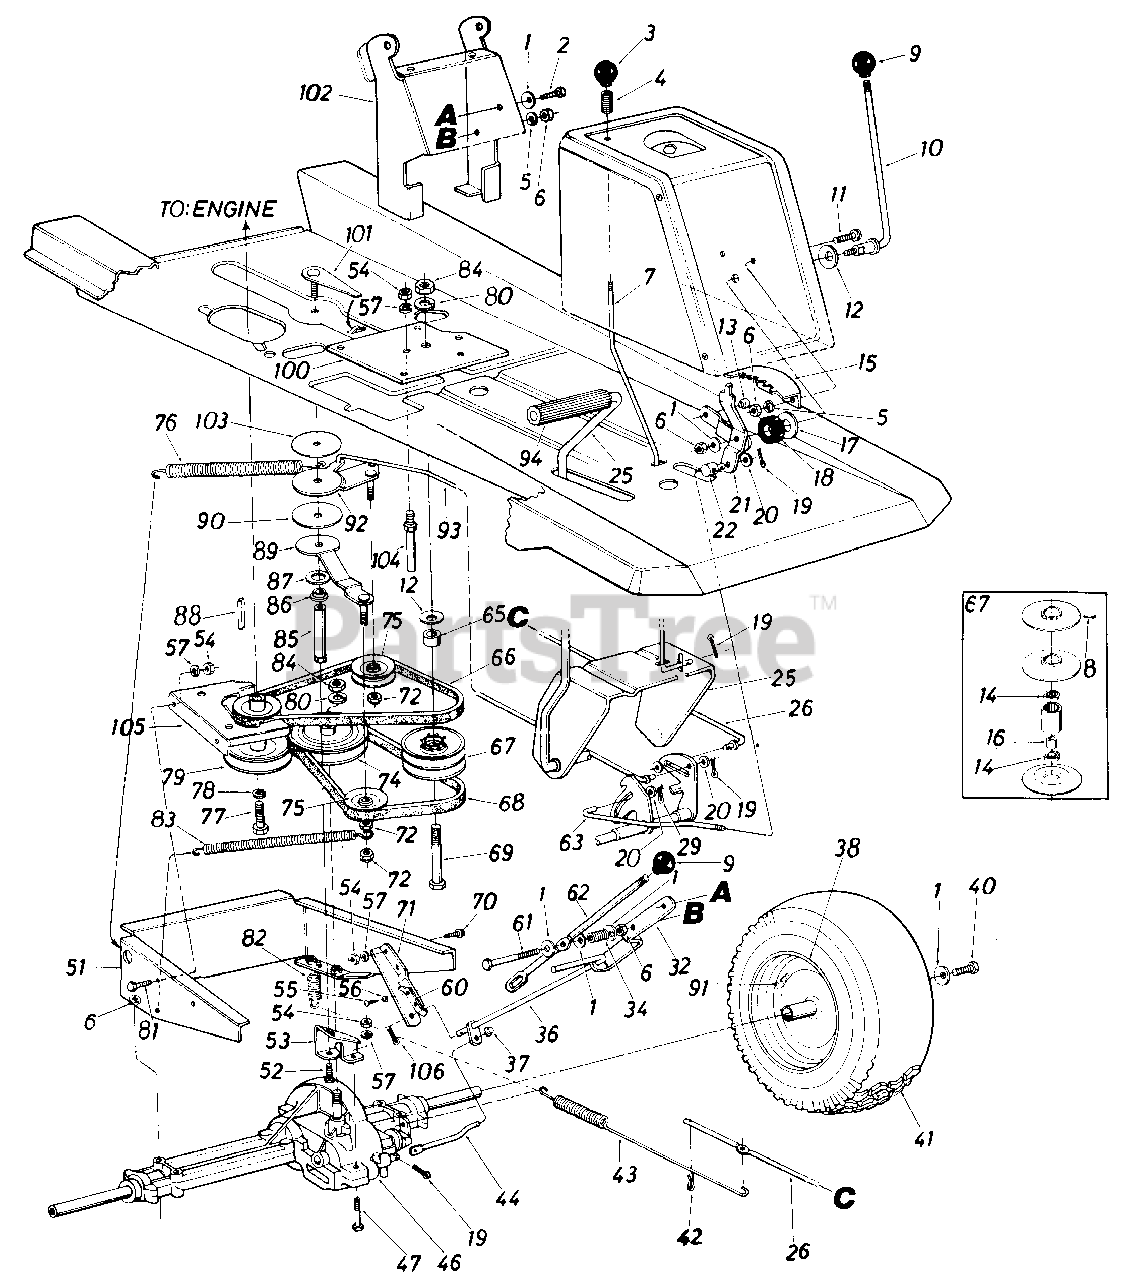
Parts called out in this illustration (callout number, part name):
1	Bell-Wash. .345" I.D. x .88" O.D.
2	Hex Wash. Hd. AB-Tap Scr. 1/4 x.62" Lg.
3	Ball Knob
4	Compression Spring
5	L-Wash. 5/16" I.D.
6	Hex Nut 5/16-18 Thd.
7	Brake Locking Rod
8	Spring Pin Spir. 5132" Dia. x.62" Lg.
9	Gear Shift Knob
10	Speed Control Lever
11	Truss Mach. Scr. 5/16-18 x .75" Lg.
12	Bell-Wash. .505" I.D. x 1.00"
14	Ball Brg. .50" I.D. x 1.38"
15	Index Bracket
16	Spacer. 50" I.D. x .69" O.D. x 1.38" Lg.
17	Fl-Wash. .50" I.D. x 1.25" O.D.
18	Rubber Wash. .50" I.D. x 1.25" O.D.
19	Cotter Pin 1/8 x 1.00" Lg.
20	Fl-Wash. .344" I.D. x .688"
21	Speed Control Lever Brkt. Ass'y.
22	Ferrule-Engagement
25	Clutch-Brake Pedal Ass'y.
26	Brake Rod
29	Intern. Cotter Pin 5/16" Dia.
32	Shift Lever Brkt.
34	Spring
36	Shift Lever Ass'y.
37	Cap Speed Nut 1/4" Rod
38	Rear Wheel Rim Only
40	Hex L-Bolt 5/16-24 x .75" Lg.
41	Rear Wheel Ass'y. Comp.
42	Cot-Pin 1/8" Dia. x 1.25
43	Ext. Spring .75" O.D. x 17.0"
44	Shift Rod
46	Transaxle Comp.
47	Hex Bolt 1/4-20 x 1.75" Lg.
53	Torque Rod Bracket
54	Hex Nut 1/4-20 Thd.
55	C-Sink AB S-Tap Scr. #8 x .50"
56	Push-ln Nut #10
57	L-Wash. 1/4" I.D.
60	Spring Switch
61	Hex Bolt 5/16-18 x 2.25" Lg.
62	Upper Shift Lever
63	Speed Control Rod
65	Spacer. 501" I.D. x .750" O.D. x .775
66	"V"-Belt 5/8" L x 35" Lg.
67	Variable Speed Pulley Ass'y.
68	"V"-Belt 5/8" L x 38" Lg.
69	Hex Bolt 1/2-13 x 4.0" Lg.
70	Hex Bolt 1/4-20 x .62" Lg.
71	Shift Lever Support
72	Hex Ins. L-Nut 3/8-24 Thd.
74	518" V-Pulley 6.0" O.D.
75	"V"-Belt Idler3.06" O.D.
76	Extension Spring .99" O.D. x 8.0" Lg.
77	Hex Bolt 7/16-20 x 1.0" Lg.
78	L-Wash. 7/16" I.D.
79	Engine Pulley
80	L-Wash. 1/2" I.D.
81	Hex Bolt 1/4-20 x .75" Lg.
82	Brake Return Ext. Spring 3.18" Lg.
83	Extension Spring
84	Hex Nut 1/2-13 Thd.
85	Torque Rod 3.835" Lg.
86	Flange Bearing .378
87	Fl-Wash. .640" I.D. x 1.24"
88	Sq. Key 1/4" x 2.00" Lg.
89	Idler Bracket Ass'y.
90	Thrust Wash. .635" I.D. x 3.50" O.D.
91	Air Valve
92	Idler Bracket Ass'y.
93	Clutch Rod
94	Foot Pad
100	Mounting Bracket Variable Speed Pulley
103	Thrust Wash. .385" I.D. x 3.50" O.D.
104	Belt Guard Pin 1/4" Dia. x 1.68" Lg.
105	Upper Engine Belt Guard
106	Cotter Pin 3/32" Dia. x .75"Lg.
